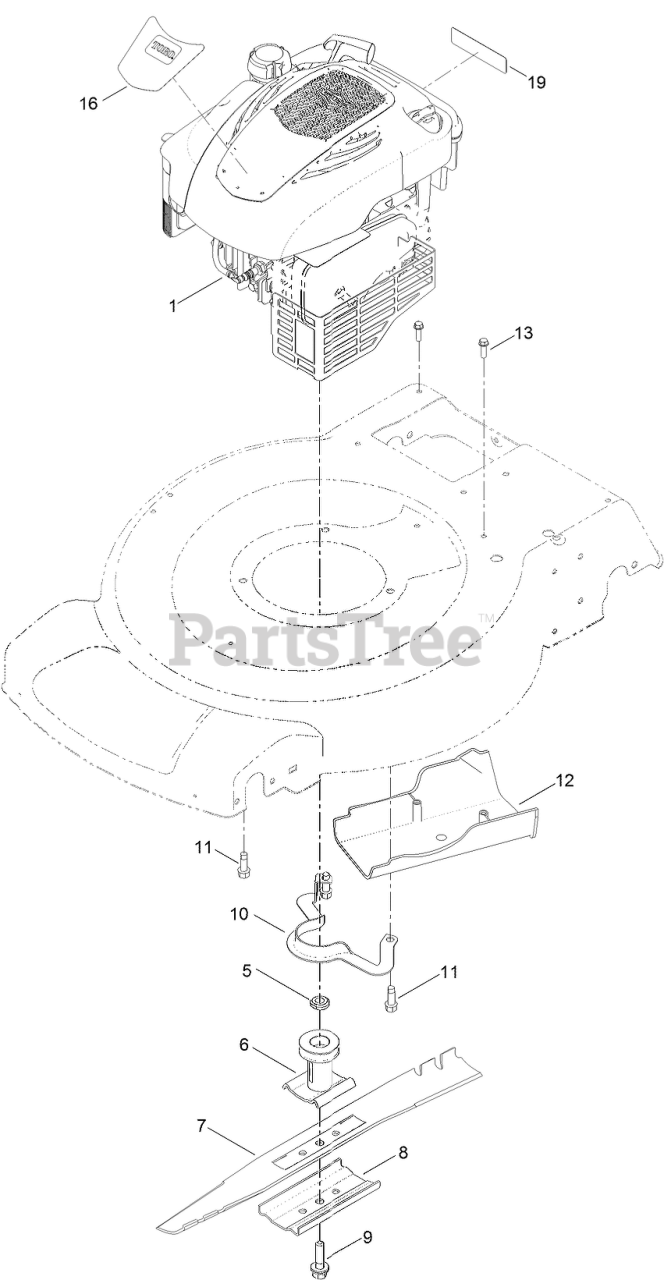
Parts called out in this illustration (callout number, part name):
5	Spacer-Driver
6	DRIVER-BLADE
7	BLADE-22 INCH
8	SUPPORT-BLADE
9	BOLT-BLADE
10	Guide-Belt
11	SCREW-TAPTITE
12	COVER-BELT
13	SCREW-HWH
16	DECAL-SHROUD
19	DECAL-ARRESTER, SPARK
